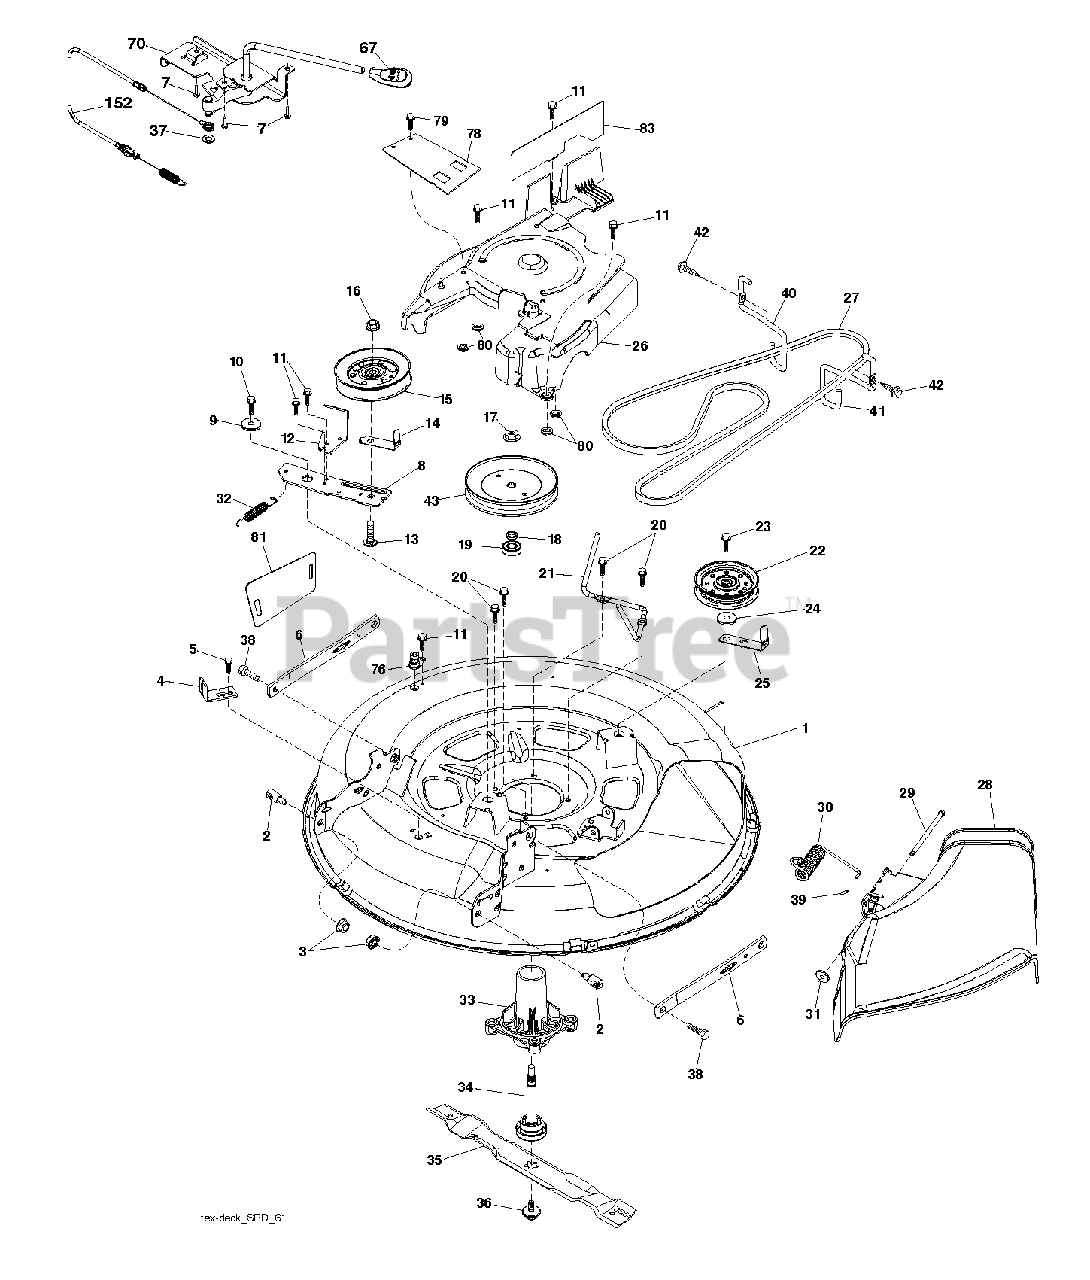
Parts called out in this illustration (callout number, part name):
1	DECK.WELDMENT.PNT.30"SRD
2	STUD.FASTNER.W/ANTI-ROTATE
3	NUT LOCK HEX FLANGE 5/16-18
4	BRACKET.CLUTCH.CABLE
5	BOLT.5/16HEX.WHS.HD
6	ARMS.SUSP.MOWER.REAR.SRD
7	SCREW.#10 X 0.750.BOS
8	ARM.IDLER.30"SRD
9	SPACER.RETAINER
10	SCREW 3/8-16X1
11	SCREW.1/4-20X5/8
12	RP ARM.BRAKE.MOWER.38"LH.TEX
13	BOLT.3/8-16X1.50
14	KEEPER, BELT IDLER
15	PULLEY.IDLER.4.25
16	NUT LOCK FLG 3/8-16 UNC
17	NUT.FLANGE.LOCK.TOP
18	WASHER.SPACER.MANDREL
20	SCREW, WASHER HEAD
21	KEEPER.BELT.MANDREL.30"
22	PULLEY.IDLER.FLAT.46.PR.DR.
23	SCREW LT
24	WASHER
25	KEEPER.BELT.30"SRD
26	COVER.ASM.MANDREL.30"
27	V-BELT.DRIVE.MOWER.30"
28	SHIELD.DEFLECT.MWR.30S.BLACK
29	PIN.HINGE.30".SRD
30	SPRING.TORSION.DEFLECT
31	NUT PUSH M
32	SPRING RETURN
33	HOUSING.MANDREL.4PT.
34	SHAFT.ASM.MDRL.N/GREASE.38
35	BLADE, MULCH.LRV30
36	BOLT.WASHER.ASM.7/16-2
37	WASHER
38	BOLT.SHOULDER
39	CAP-SLEEVE LT
40	KEEPER.BELT.ENGINE.LH.LT.SRD
41	KEEPER.BELT.ENGINE.RH.LT.SRD
42	SCREW, 3/8-16X3/4
43	PULLEY, MANDREL 6.5 PD
67	HANDLE.CLUTCH.CABLE.LT
70	CLUTCH.ASM.MANUAL.LT.PRED
76	PORT.WASHOUT
78	GUARD ARM CLUTCH
79	SCREW.HI-LO.CONSOLE
80	PALNUT 1/4
81	SHIELD SUSPENSION
83	GUARD LEFT
152	CABLE.CLUTCH.MANUAL.
